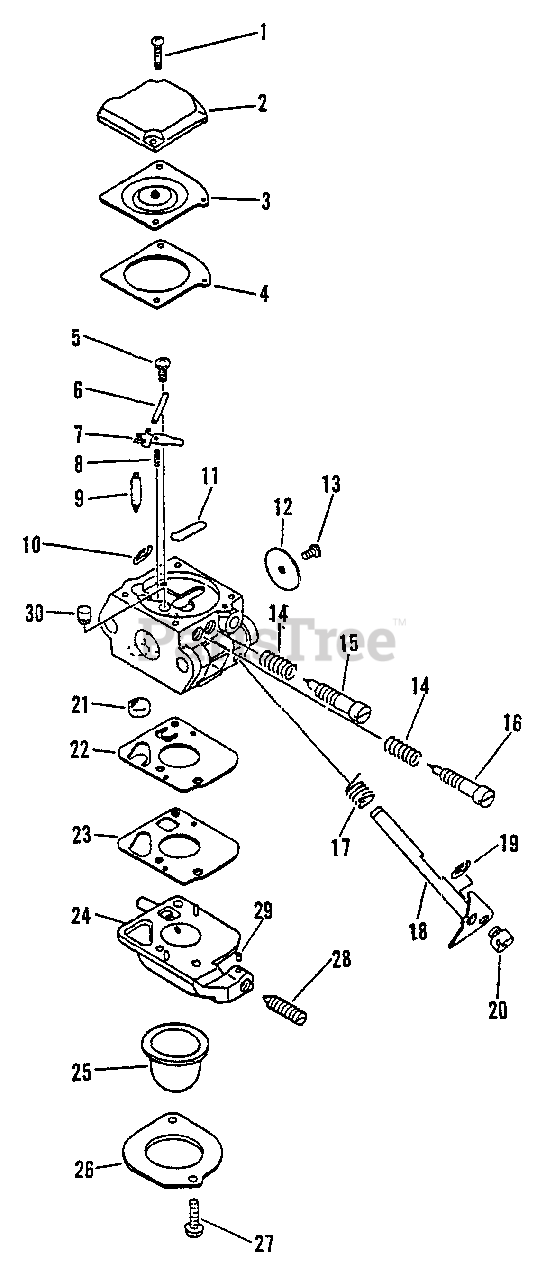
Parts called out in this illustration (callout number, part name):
2	COVER, METERING
3	DIAPHRAGM
4	GASKET, METERING
5	SCREW, METERING LEVER PIN
6	PIN
7	LEVER, METERING
8	SPRING
9	VALVE, NEEDLE
10	RING, RETAINING
11	PLUG, WELCH
12	VALVE, THROTTLE
15	NEEDLE - HIGH SPEED
16	NEEDLE - MIXTURE
17	SPRING, RETURN
18	SHAFT, THROTTLE
19	RING, RETAINING
20	SWIVEL
21	STRAINER
22	DIAPHRAGM, PURGE
23	GASKET, PURGE
24	BASE, PURGE
25	BULB, PURGE
26	RETAINER, PURGE BULB
27	SCREW, RETAINER
28	SCREW
29	PIECE, FRICTION
30	NOZZLE, CHECK VALVE
